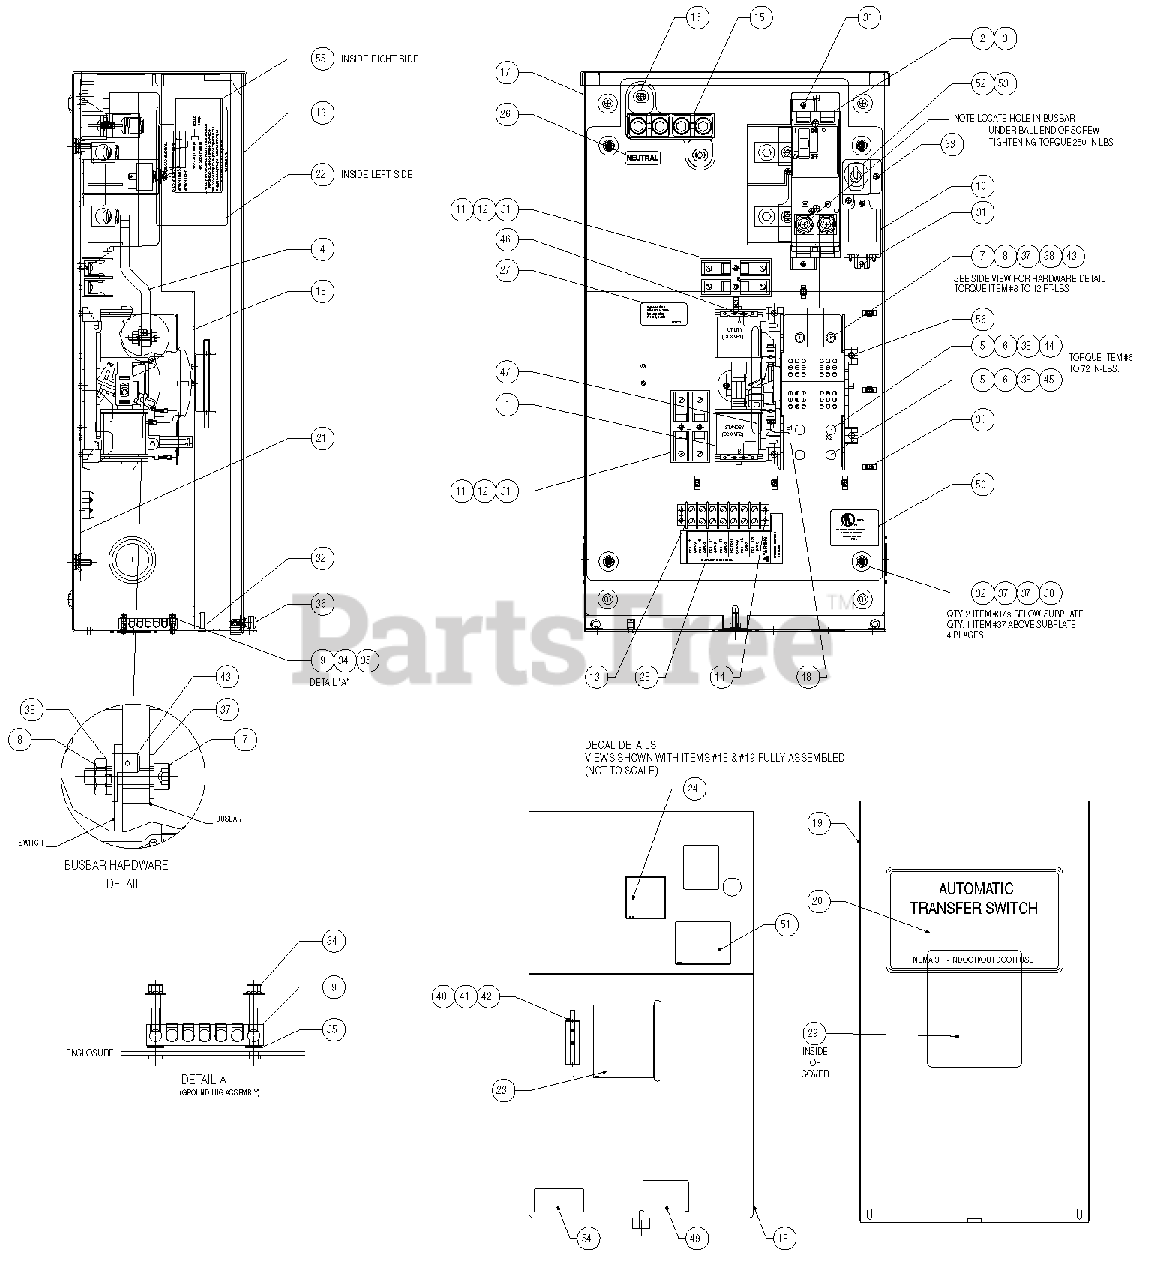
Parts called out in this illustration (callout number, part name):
1	TRANSFER SW-HSB 200A 2P 250V
2	CIRCUIT BREAKER 0200A 2P 120/240V S QN
3	BASE QN CIRCUIT BREAKER
4	BUSBAR 200A HSB XFER SW
5	LUG SLDLSS 250-#6 AL/CU
6	SCREW BHSC 1/4-20 X 3/8
7	SCREW SHC 1/4-20 X 1 G8.8 NZ
8	NUT HEX 1/4-20 STEEL
9	GROUND BAR (5)4-14 AWG CONN
10	RELAY PNL 12VDC DPDT 10A@240VA
11	FUSEBLOCK 30A 600V 2POS W/SQ
12	FUSE 5A X BUSS
13	BLOCK TERM 20A 7 X 6 X 1100V
14	RIVET POP .156 X .675 AL
15	ASS'Y-NTRL BL150-200A
16	SCREW HHTT M6-1.0 X 12 ZINC
17	WELDMENT TRANSFER SWITCH BOX
18	COVER INSIDE XFER SWITCH BOX
19	COVER TRANSFER SWITCH BOX
20	DECALTRANSFER SWITCH
21	SUBPLT XFER SW HSB
22	DECAL SWITCH RATING
23	DECAL WARN MANUAL OPER HANDLE
24	DECAL SERVICE DISCONNECT
26	DECAL NEUTRAL
27	DECAL FUSE REPLACEMENT
28	DECAL TERMINAL STRIP
29	DECAL TEST SEQ.2P TS HS 3R
30	HOLDER CABLE TIE
31	SCREW HHTT M4-0.7 X 8 BP
32	NUT HEX M6 X 1.0 G8 YEL CHR
33	SCREW HHTT M5-0.8 X 10 BP
34	SCREW HHTT M4-0.7 X 16 BP
35	WASHER SHAKEPROOF EXT #8 STEEL
36	SCREW THUMB 1/4-20 X 1/2 W/SHLD
37	WASHER FLAT 1/4-M6 ZINC
38	WASHER LOCK M6-1/4
40	BRACKET ARM EXTENDER
41	SCREW HWHS #6-25 X 3/8
42	ARM EXTENDER PIN
43	90 DEGREE UP SPADE CONNECTOR
44	90 DEGREE DN SPADE CONNECTOR
45	STRAIGHT SPADE CONNECTOR
48	WIRE E1
49	DECAL TERMINAL SHOCK HAZARD
50	DECAL-UL LIST HSB
51	DECAL-SERVICE DISCONNECT SWITCH
52	BRACKET SERVICE SWITCH
53	TOBBLE SWITCH, SERVICE
54	DECAL LIVE-CIRCUIT
55	DECAL XFER SWITCH DATA SE 200A
56	SCREW HHTT M5-0.8 X 16
